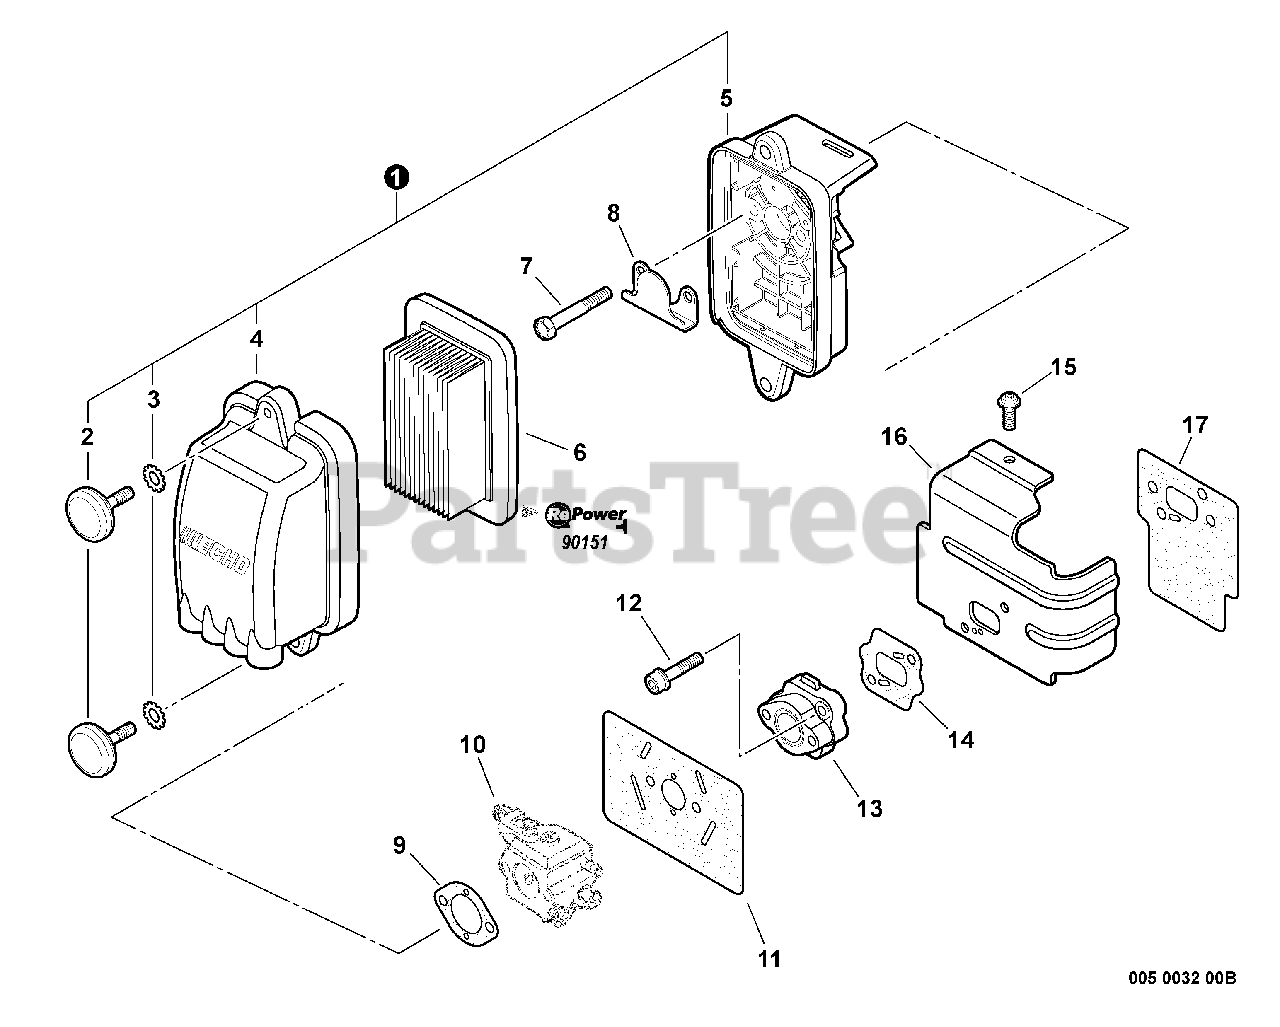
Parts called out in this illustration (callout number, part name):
1	FILTER KIT, AIR
2	THUMBSCREW
4	COVER, AIR FILTER
5	CASE ASSY, AIR FILTER
6	FILTER, AIR
7	BOLT 5×60
8	PLATE, PREVENT
9	GASKET, INTAKE
10	CARBURETOR
11	GASKET, INTAKE
12	BOLT 5×25
13	INSULATOR, INTAKE
14	GASKET, INTAKE
15	SCREW 5×10
16	COVER, CYLINDER
17	HEAT SHIELD, INTAKE
18	TUNE-UP KIT - REPOWER
